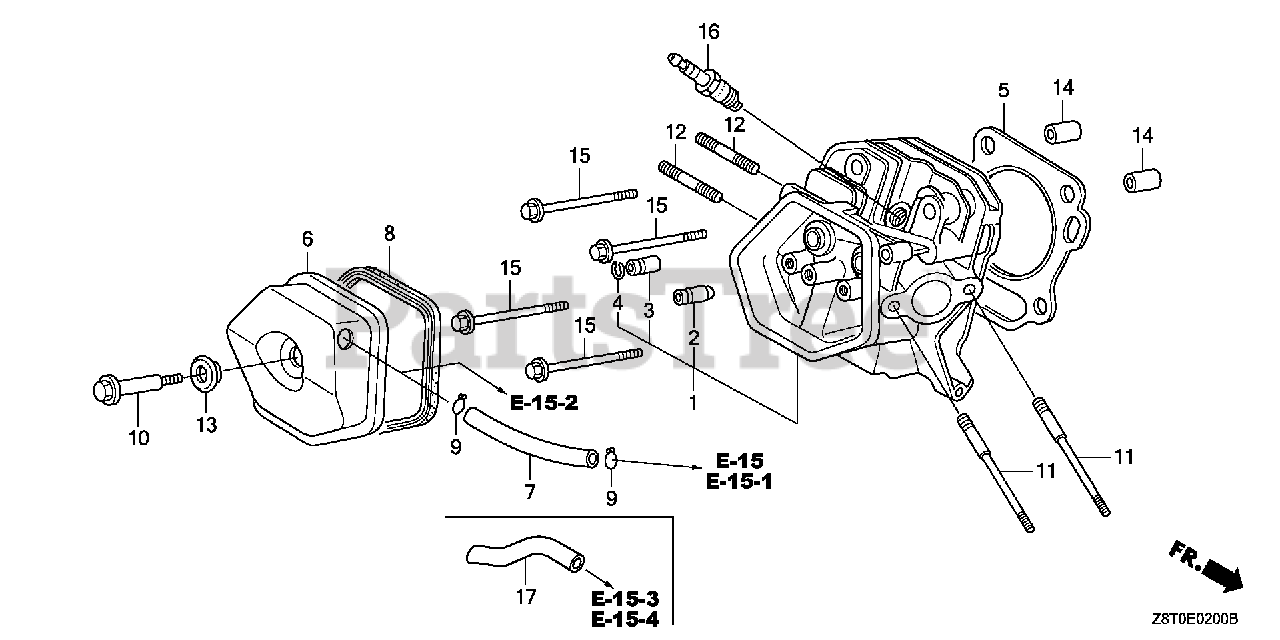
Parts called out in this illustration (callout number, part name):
1	CYLINDER HEAD
2	GUIDE, VALVE (OVER SIZE)
3	GUIDE, EX. VALVE (OVER SIZE)
4	CLIP, VALVE GUIDE
5	GASKET, CYLINDER HEAD (NIPPON LEAKLESS)
6	COVER, HEAD (BREATHER TUBE JOINT)
7	TUBE, BREATHER
8	GASKET, HEAD COVER
9	CLIP, BREATHER TUBE
10	BOLT, HEAD COVER
11	BOLT, STUD (8X131.5)
12	BOLT, STUD (8X32)
13	WASHER, HEAD COVER
14	PIN, DOWEL (12X20)
15	BOLT, FLANGE (10X80)
16	SPARK PLUG (BPR5ES) (NGK)
16	SPARK PLUG (W16EPR-U) (DENSO)
16	SPARK PLUG (BPR6ES) (NGK)
16	SPARK PLUG (W20EPR-U) (DENSO)
